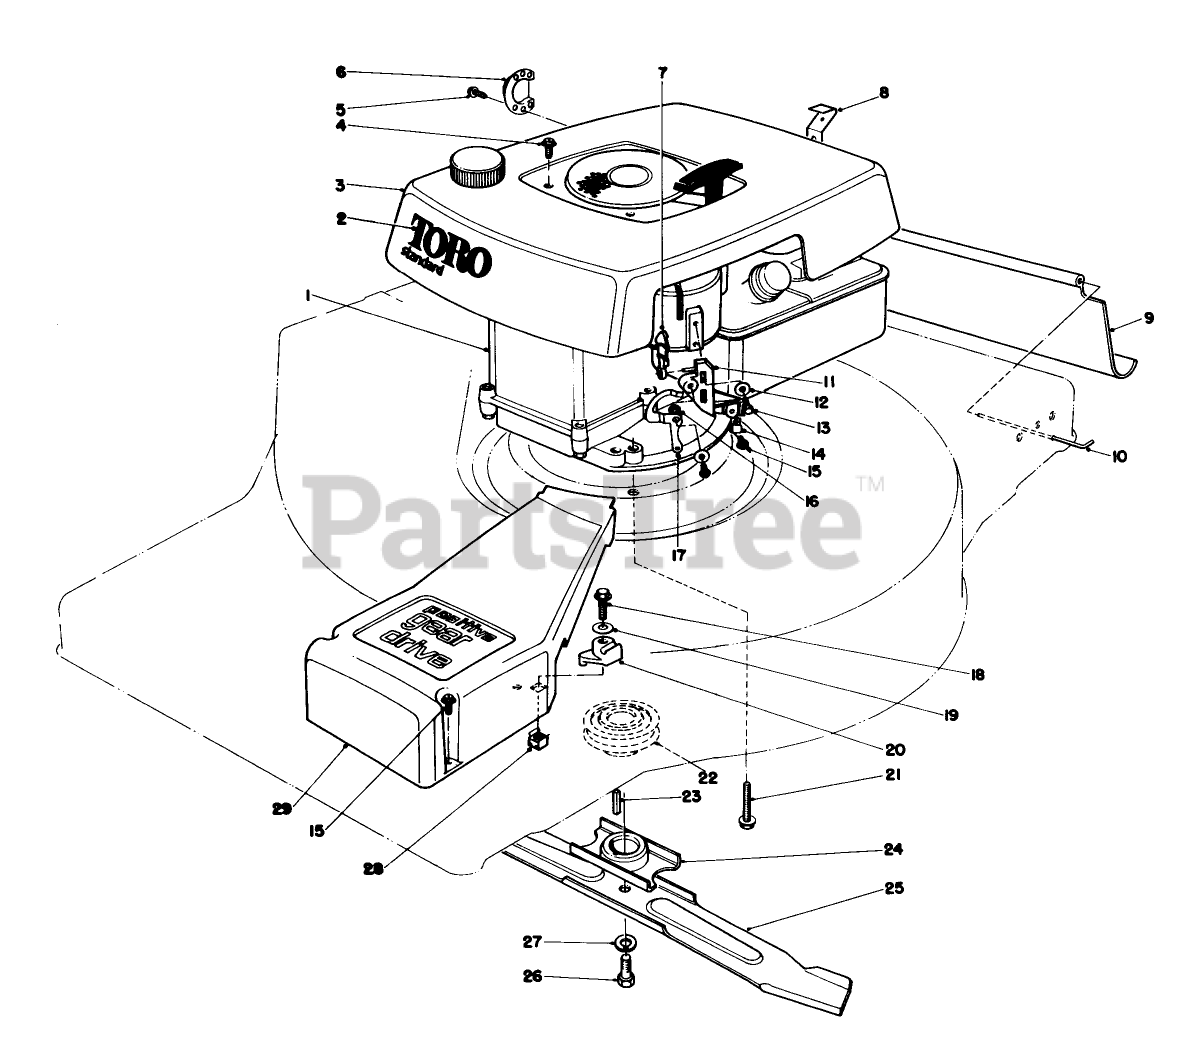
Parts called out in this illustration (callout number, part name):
1	Engine
2	Decal Shroud
3	SHROUD
4	8X1/2 SELF TAP SCREW
5	SCREW W/ENGINE
6	Deflector
7	INTERLOCK LEVER
8	Bracket Control
9	SAF SHIELD REAR
10	SHIELD ROD
11	CABLE & PIVOT BLOCK
12	WASHER-FLAT
13	SCREW-SHWH
14	CLAMP
15	SCREW-HWHTF
16	BUSHING
17	CAM INTERLOCK
19	WASHER-FLAT
20	CABLE BOSS
21	SCREW-HWHTF
22	DRIVER PULLEY
23	KEY-SQUARE
24	Blade Retailer
25	Blade
26	SPECIAL SCREW
27	WASHER-LOCK
28	SPEED NUT
29	Belt Cover
